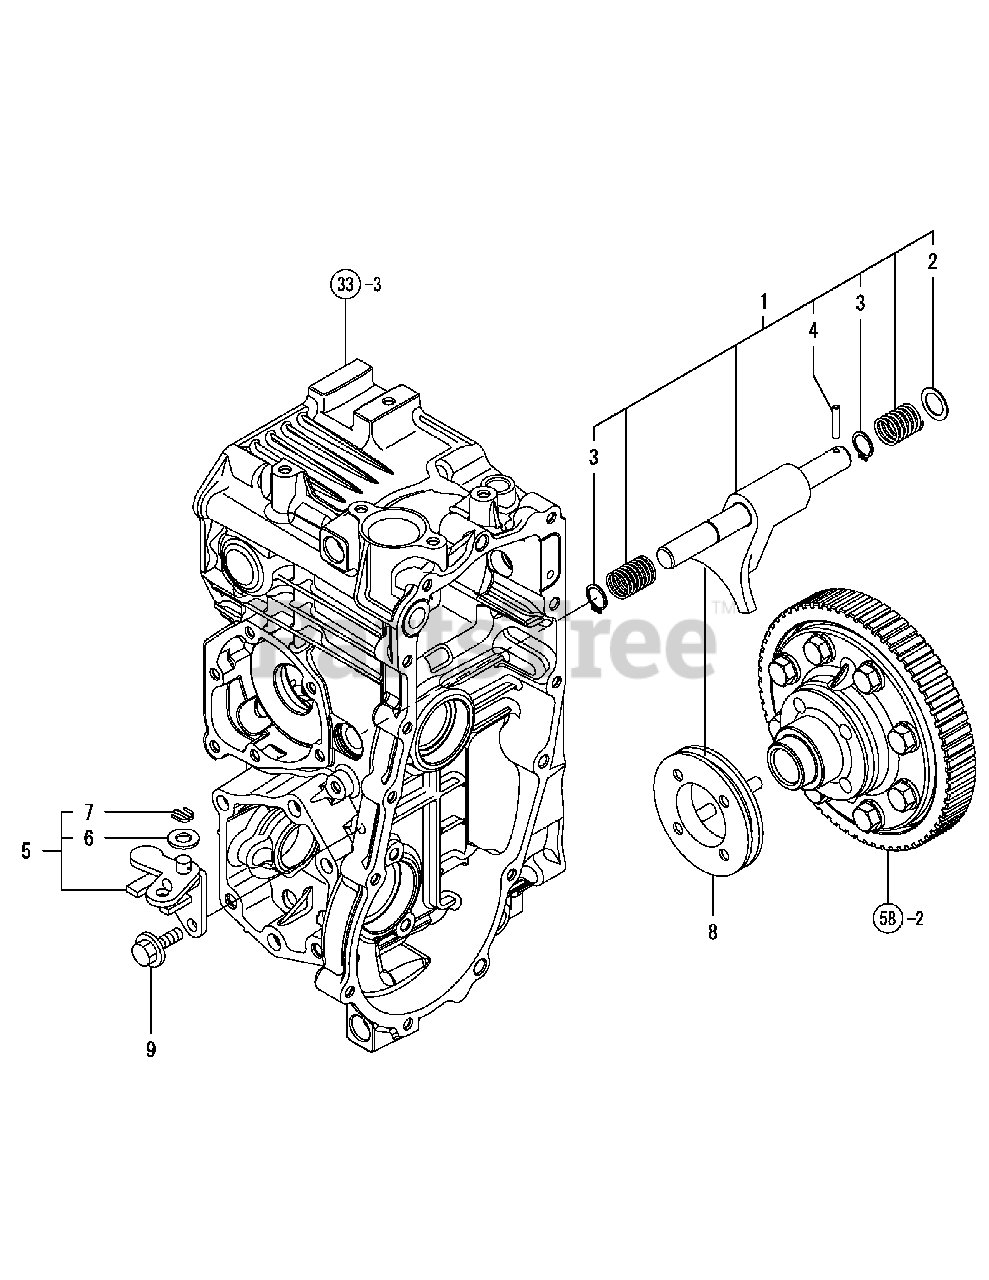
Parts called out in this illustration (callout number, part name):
1	FORK KIT, DIFF.LOCK
2	SPACER 16.5X24X1
4	PIN 4X25, SPRING
5	FULCRUM KIT, DIFF.
6	WASHER 10, POLISHED
7	COTTER PIN 2.0X20
8	SLIDER,DIFF. LOCK
